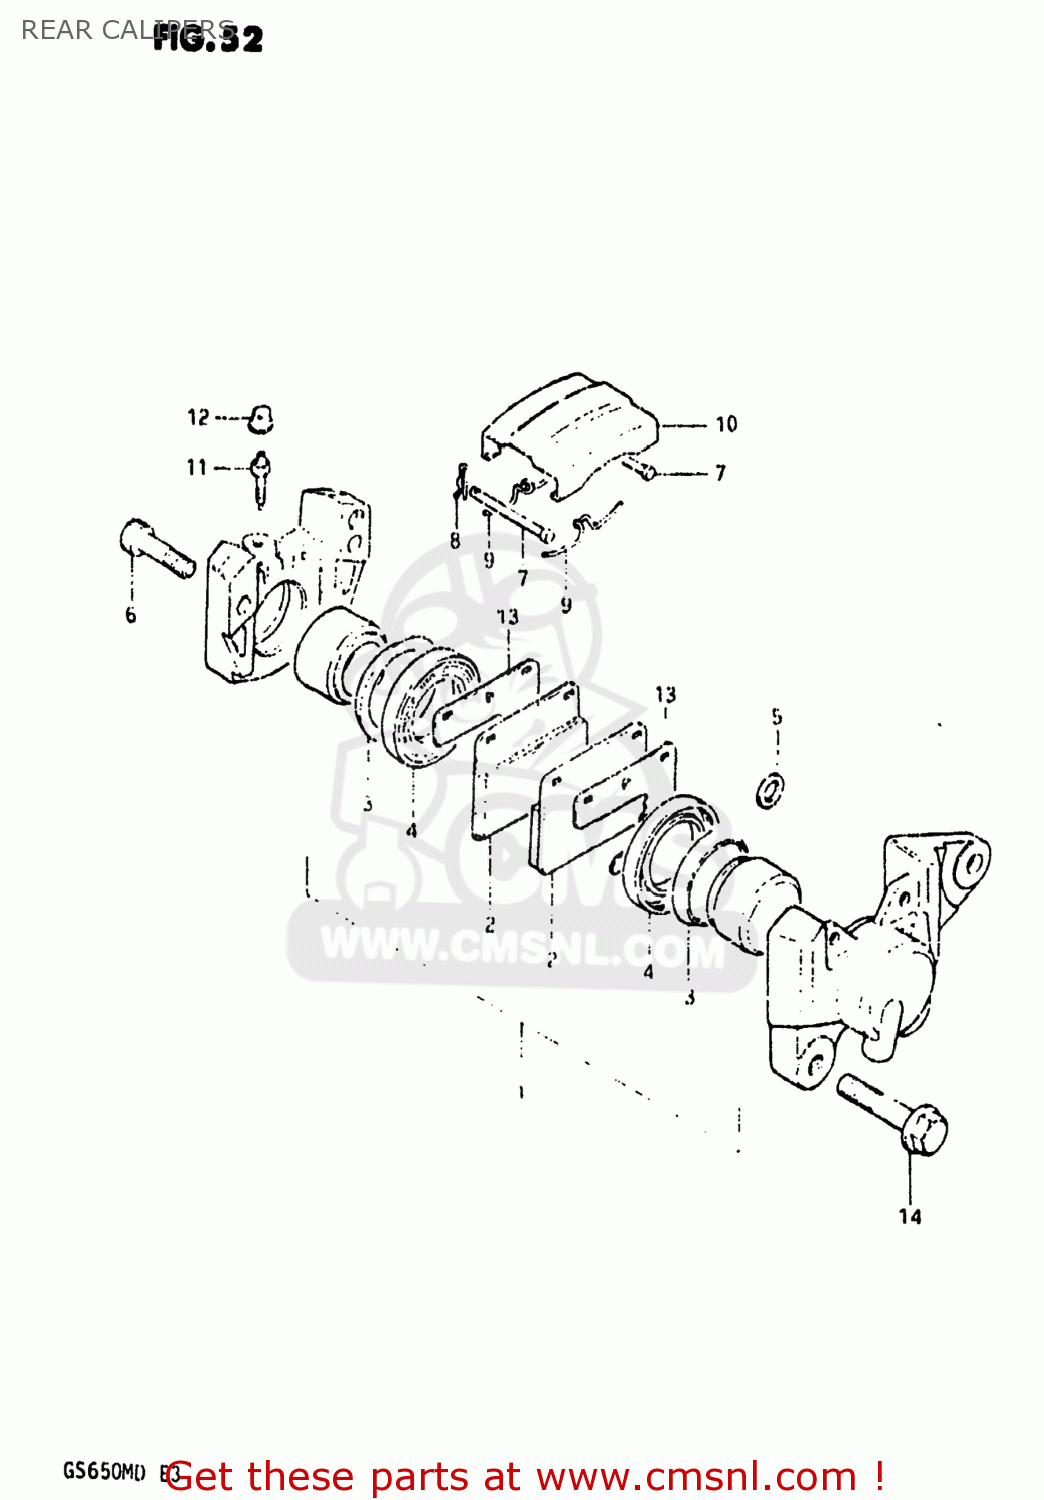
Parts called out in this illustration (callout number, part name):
1	PISTON SET
2	PAD,BRAKE (MCA)
3	SEAL.PISTON
4	BOOT,PISTON
5	SEAL,JOINT
6	BOLT,CALIPER HOUSING
7	PIN,PAD
8	CLIP,PAD PIN
9	SPRING
10	COVER,DUST
11	BLEEDER
12	CAP,BREATHER
13	SHIM,RR CALIPER
14	BOLT
